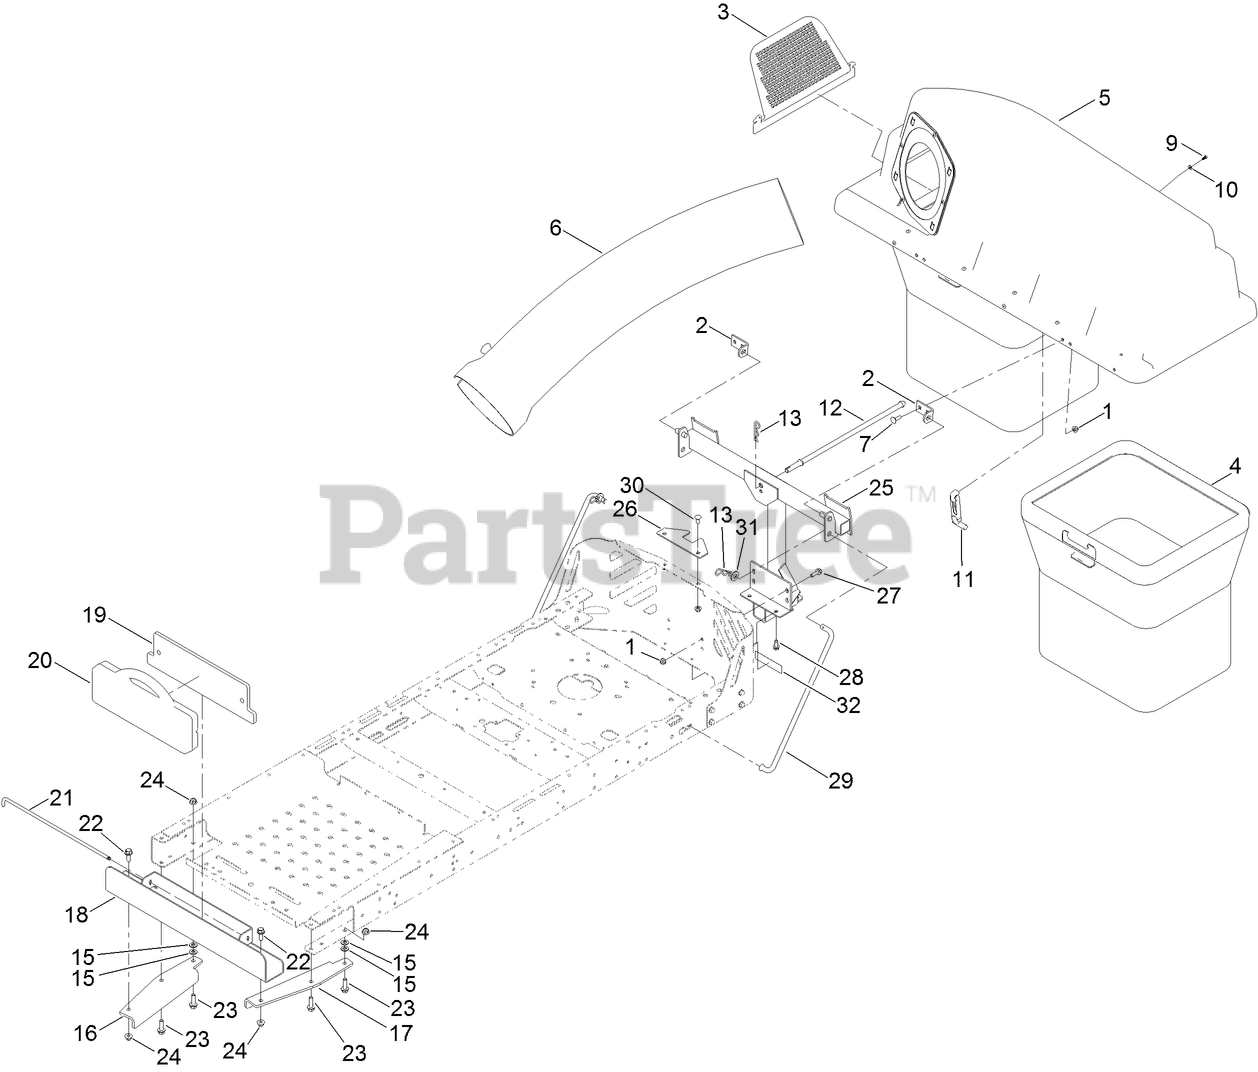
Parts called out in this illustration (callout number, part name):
1	NUT-HF
2	BRACKET-HOPPER PIVOT
3	SCREEN-BAGGER
4	BAG ASM
5	BAGGER TOP ASM
6	TUBE-BAGGER
7	BOLT-CARR
9	SCREW-PLASTIC, PTH
10	WASHER-PLAIN
11	LATCH-RUBBER
12	ROD-HOOD, DOWN (HOLD)
13	PIN-HAIR
15	WASHER-FLAT
16	BRACKET-BAGGER WEIGHT, RH
17	BRACKET-BAGGER WEIGHT, LH
18	CHANNEL-WEIGHT, BAGGER
20	WEIGHT-35 POUND
21	ROD, WEIGHT LOCK
22	SCREW-HHF
23	SCREW-HHF
24	NUT-HF, NI
25	PIVOT FRAME ASM
26	BRACKET-STABILIZER
27	SCREW-HHF
28	SCREW-HWHTF
29	ROD-SUPPORT, CZ
30	BOLT-CARR
31	WASHER-FLAT
